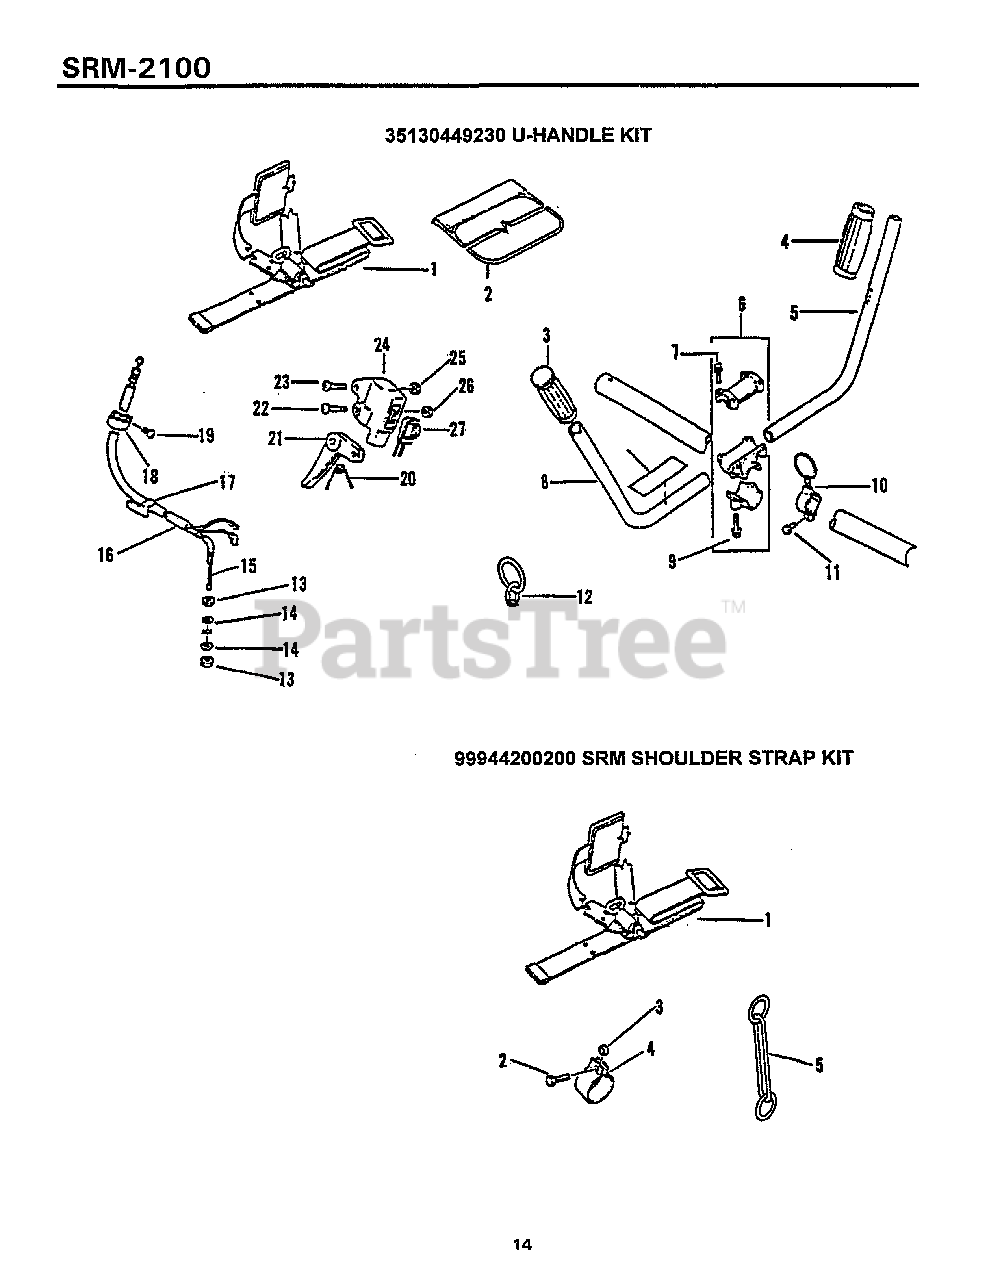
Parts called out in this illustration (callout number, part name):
1	Harness Asy
2	Pad, Waist
4	Link, Hook
5	Handle (Right)
6	Bracket Set
7	Bolt 5x25
8	Handle (Left)
9	Bolt 6x30
10	Hook, Lifting
11	Bolt 5x12
12	Ring, Harness
15	Cable, Bowden
16	Tube
20	Spring, Trigger Return
21	Trigger, Throttle
22	Screw 5x25
24	Holder, Tirgger
27	Switch, Ignition
